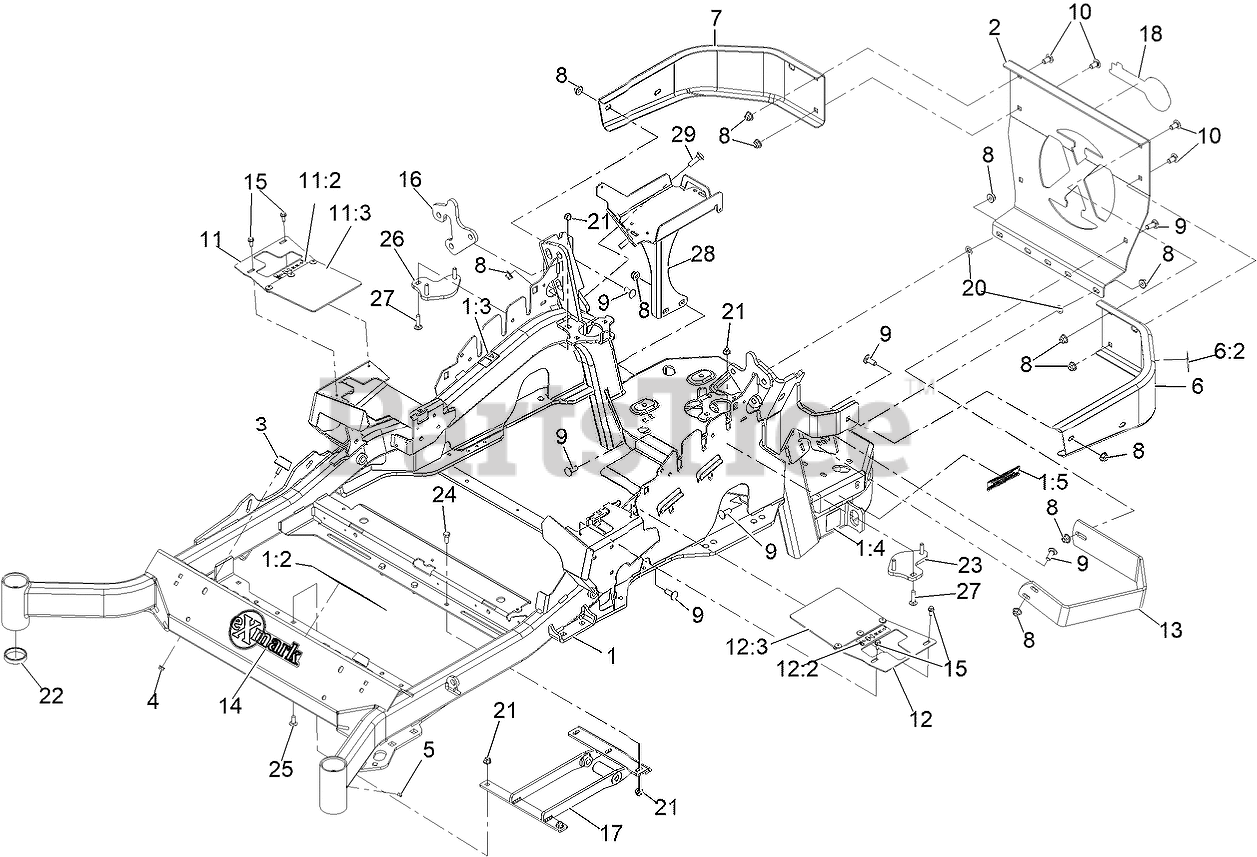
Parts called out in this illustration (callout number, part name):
1	MAINFRAME SERVICE ASM - 60
1:2	DECAL-DANGER
1:3	DECAL-WARNING
1:4	DECAL-HAZARD, PINCHED FINGER
1:5	DECAL-ARRESTOR, SPARK
2	PLATE,REAR GUARD
6	LH BUMPER ASM
6:2	DECAL-WARNING
7	BUMPER-RH
8	NUT-HF, NI
9	SCREW-CARR
10	SCREW-CARR
11	RH MOTION CONTROL COVER A
11:2	DECAL-CONTROL, MOTION
11:3	FLAP-RUBBER
12	LH MOTION CONTROL COVER A
12:2	DECAL-CONTROL, MOTION
12:3	FLAP-RUBBER
13	GUARD-MUFFLER
14	DECAL-EXMARK
15	SCREW-HWH
16	PLATE-MOUNT, SHOCK
17	MOUNT-LOWER
18	DECAL, EXMARK LOGO
20	NUT-PUSH
21	NUT-HF, NI
22	CUP-BEARING
23	LH PLATE ASM (W/STUDS)
24	SCREW-HH
25	SCREW-CARR
26	RH PLATE ASM (W/STUDS)
27	Bolt-Carriage 5/16-18 X 1 1/4
28	BATTERY MOUNT ASM
29	BOLT-CARR
